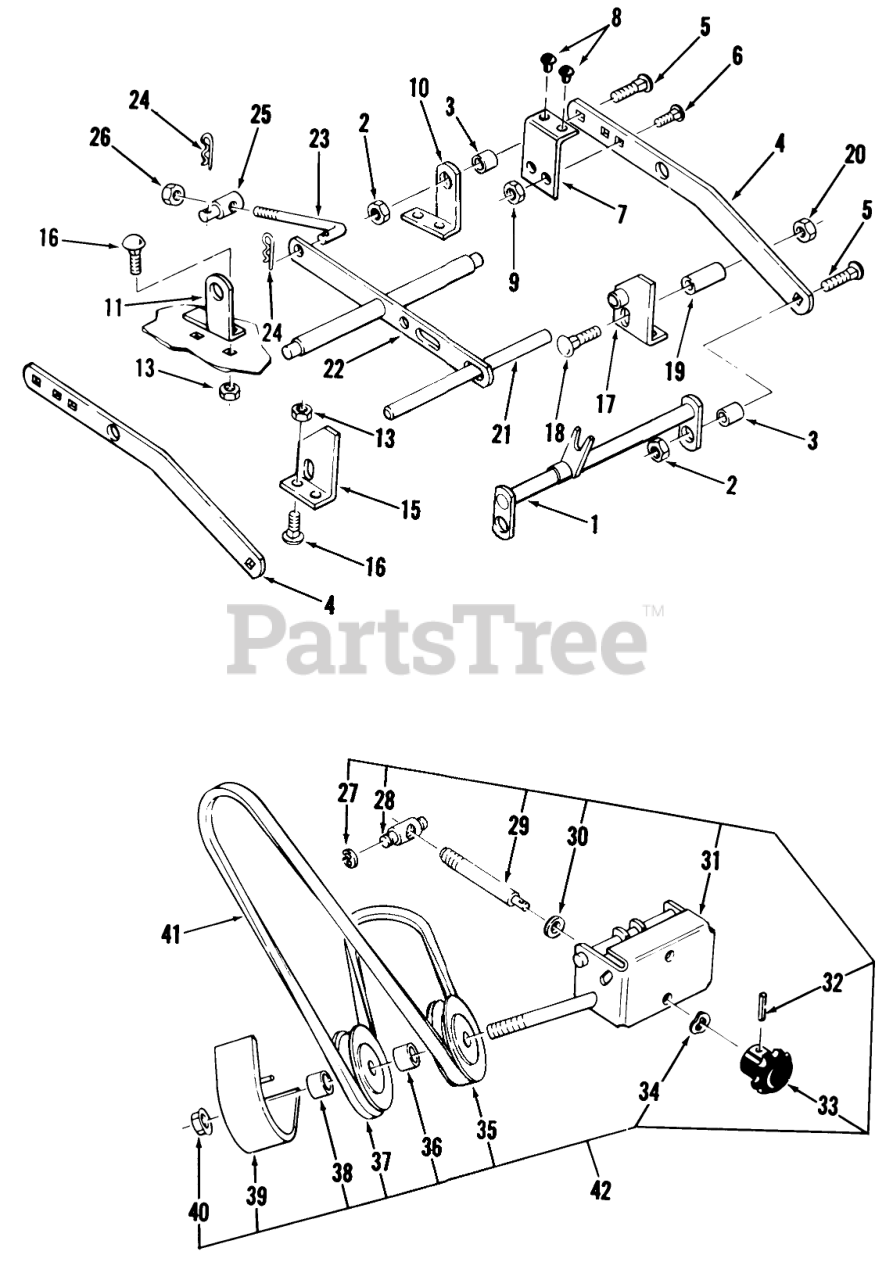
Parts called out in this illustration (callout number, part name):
1	Hitch
2	LOCKNUT-FLANGE
3	SPACER
4	Bar Draft
5	Bolt
6	Bolt-Carriage
7	Metal Bumper
8	BUMPER-RUBBER
9	Nut
10	LH Rear Bracket
11	Rear Bracket RH
13	Nut
15	Front Bracket RH
16	Bolt-Carriage
17	Front Bracket LH
18	CARRIAGE BOLT -4
19	SPACER-BEARING
20	Nut
21	Front Shaft
22	Leveler
23	ROD-LEVEL ADJUST
24	Hairpin
25	TRUNNION-LIFT
26	NUT
27	RING-RETAINING
28	TRUNNION-DOUBLE
29	ROD ADJ
30	Washer
31	Front Support
32	PIN-ROLL
33	KNOB-ADJUSTMENT
34	Spring Washer
35	Pulley-V
36	SPACER
37	PULLEY-FLAT IDLER
38	SPACER-OUTER
39	Belt Cover
40	Nut 3/4-16 MF
41	V-BELT
42	ASM-SUPPORT,IDLER
